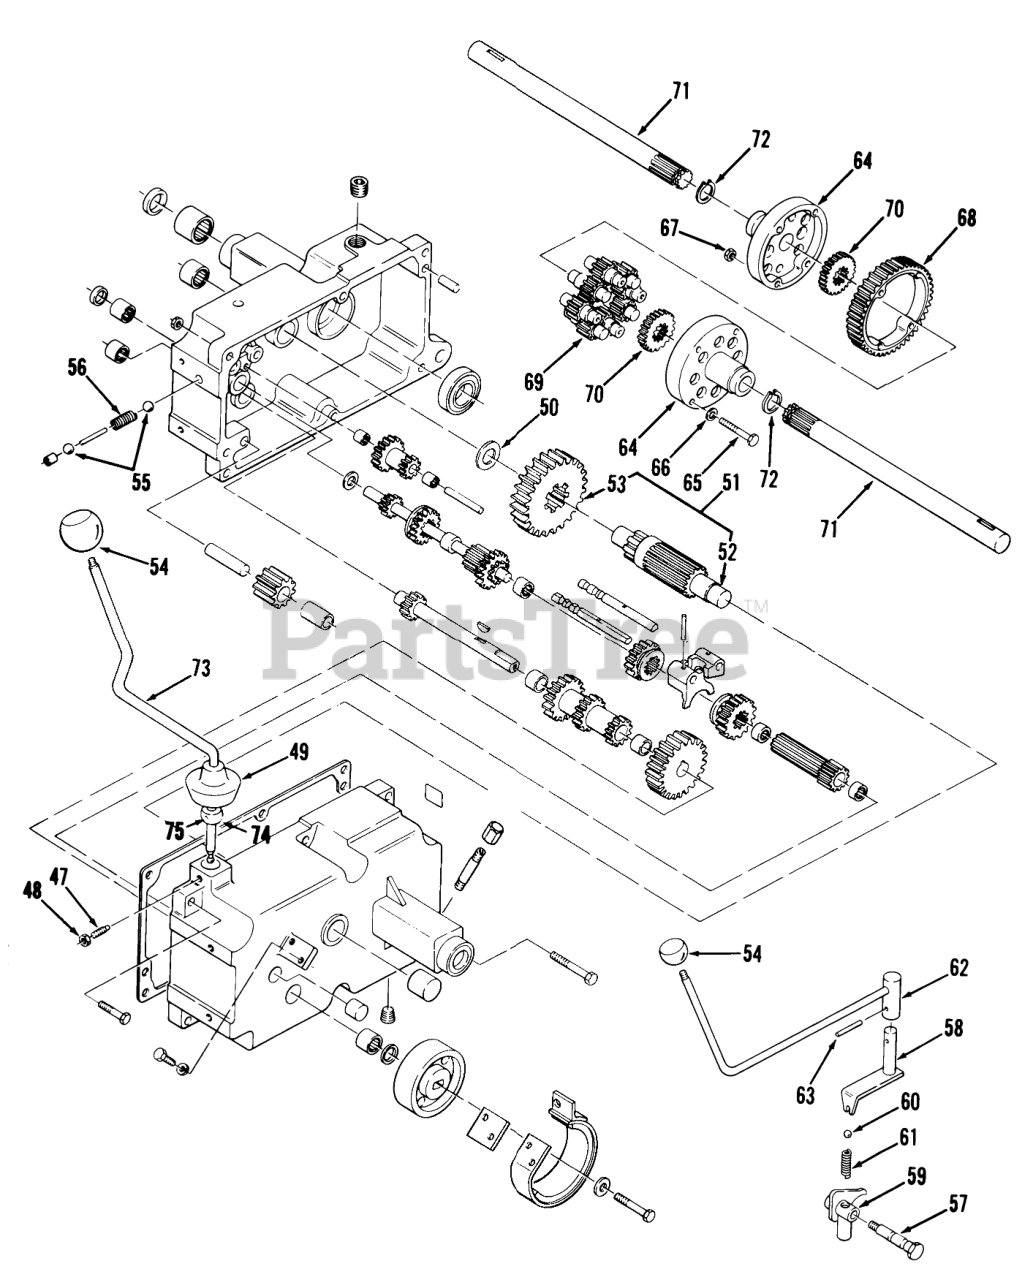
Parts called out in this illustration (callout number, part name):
47	SETSCREW
48	Nut
49	COVER-DUST
50	WASHER-THRUST
51	GEAR ASM
52	PINION SHAFT
54	SHIFT KNOB
55	BALL-DETENT
56	SPRING-SHIFT STOP
57	BOLT-DETENT
58	SHIFT ASM
59	Shift Fork
60	BALL-DETENT
61	SPRING-SHIFT STOP
62	Shift Lever HI-Low Range
63	PIN-SPIROL
64	DIFFERENTIAL END CAP
65	BOLT-HEX
66	WASHER
67	Nut
68	GEAR-DIFFERENTIAL RING, 43T
69	GEAR-PINION, 11T
70	GEAR-AXLE DIFFERENTIAL
71	AXLE-REAR
72	RING-SNAP
73	Gear Shift Lever
74	Collar
75	Roll Pin 5/12 x 7/8
